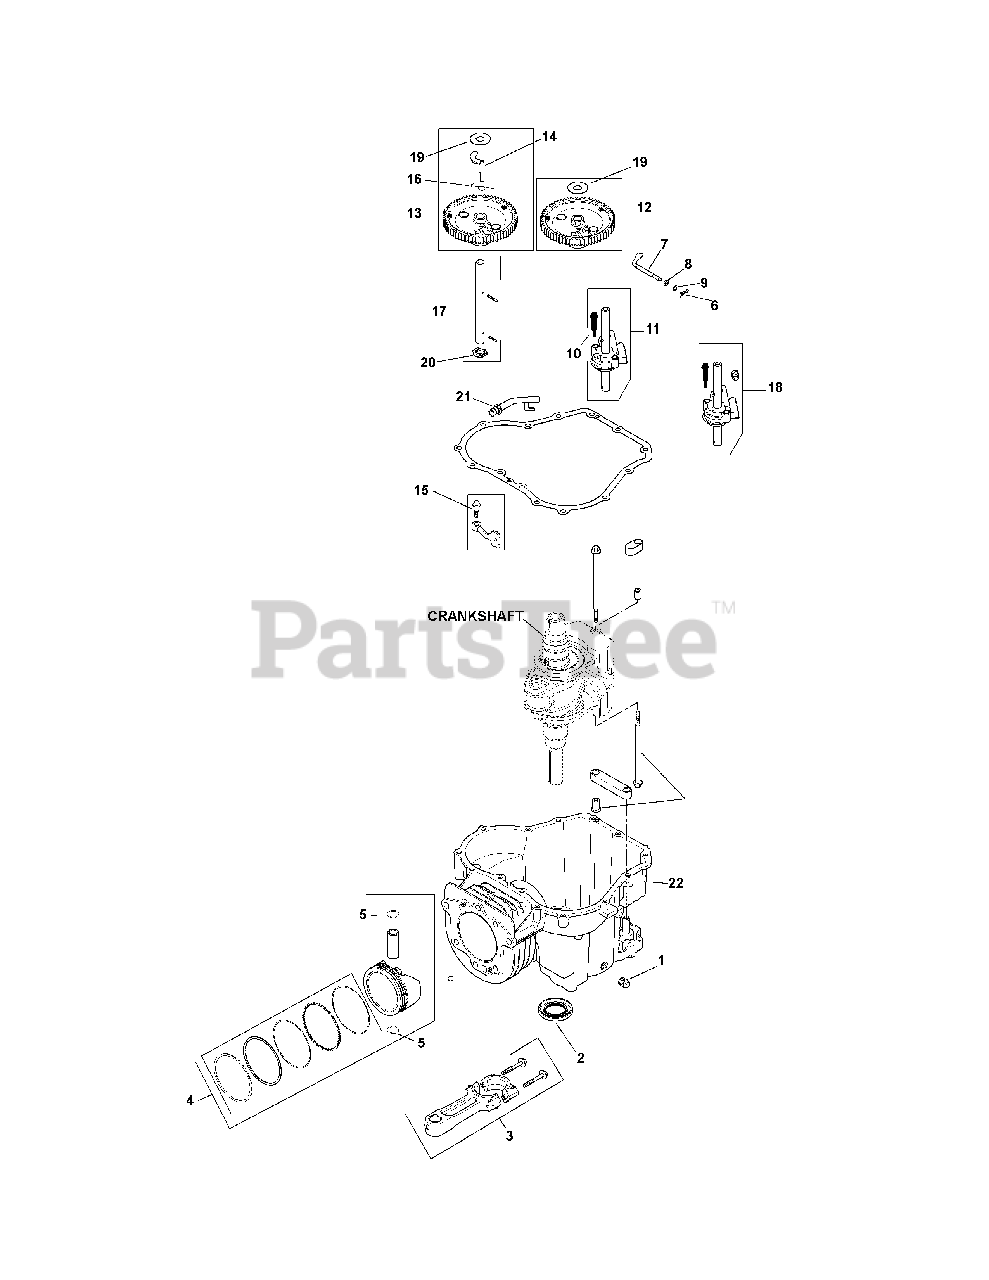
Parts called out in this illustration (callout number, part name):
1	Square Head Pipe Plug, 3/8
3	Connecting Assembly Rod
4	Piston W/ Ring Set Kit, 94mm
5	Piston Pin Retainer
6	Hitch Pin Clip
7	Governor Cross Shaft
8	Flat Washer, 6 Mm
9	Flat Washer, 1/4
10	Shd. Thd. Frm. Screw
11	Oil Pump Assembly Kit
12	Cam Lobe Assembly
13	Cam Gear Assembly
14	Acr. Weight and Follower Kit
15	Shd. Thd. Frm. Screw, M6 x 1 x 26
17	Cam Center Shaft Kit
18	Oil Pump Kit (Shallow 10mm)
19	Thrust -Acr. Washer
20	Thrust Washer
21	Drainback Tube
22	Crankcase (Use: Short Block)
